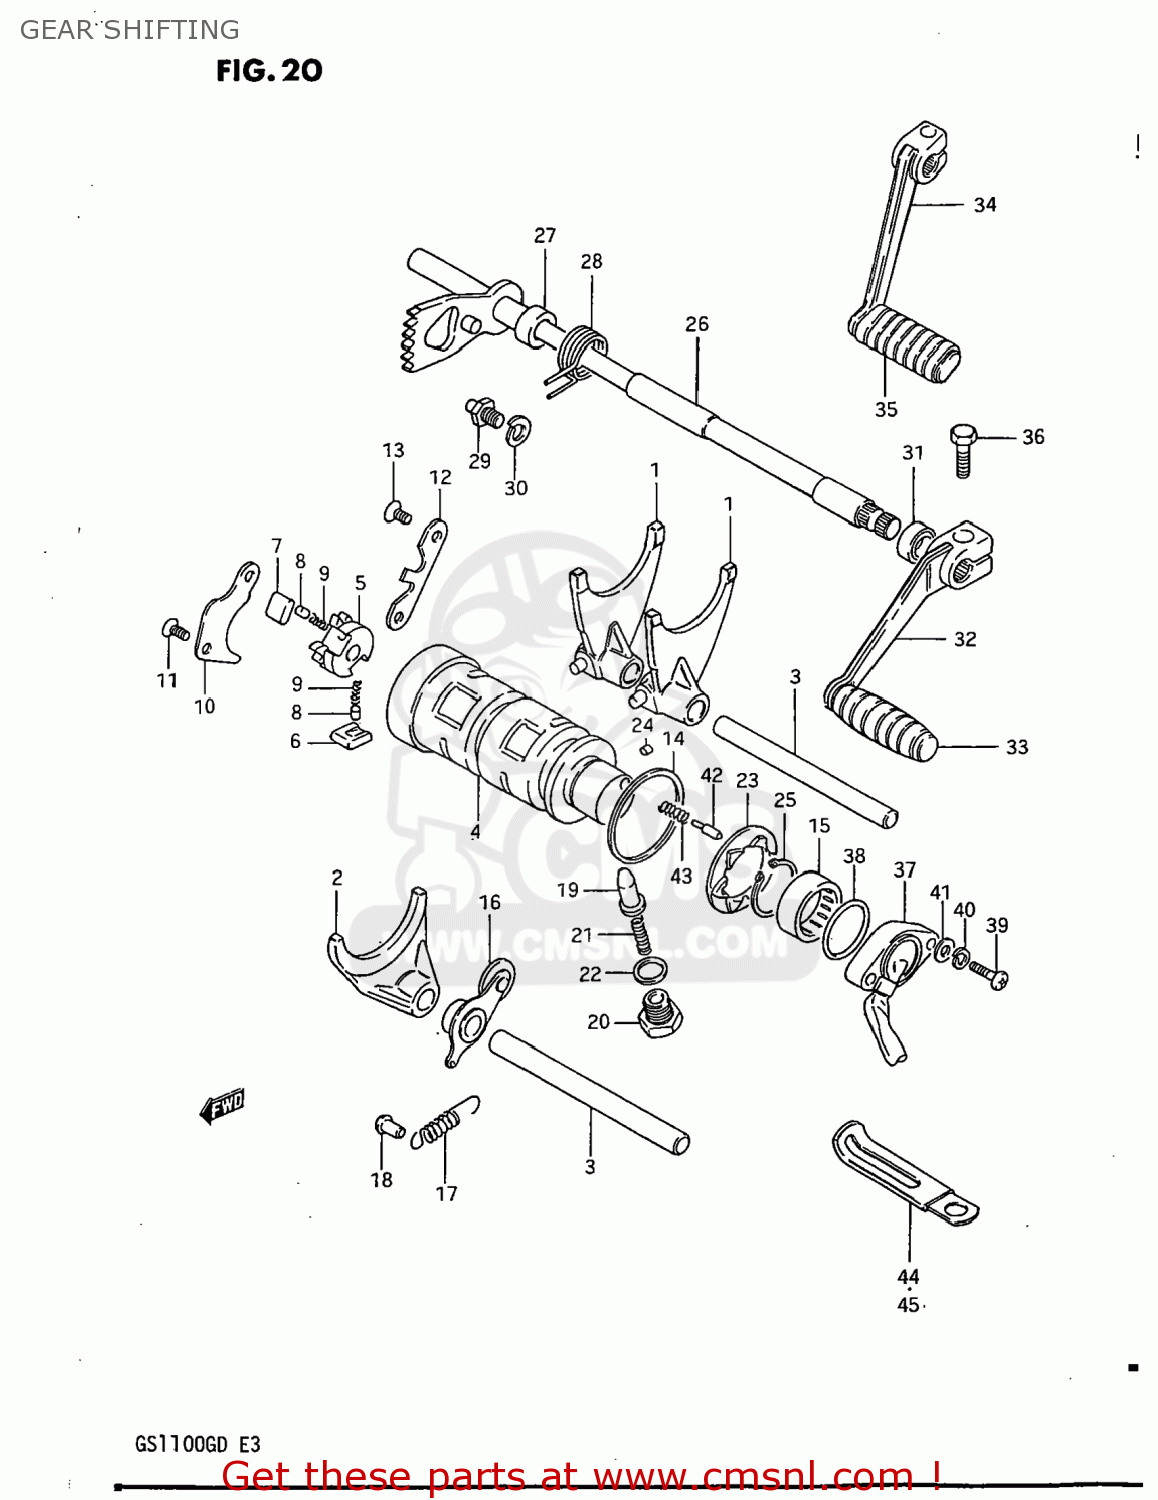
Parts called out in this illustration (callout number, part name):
1	FORK,GEAR SHIFT NO.1
2	FORK,GEAR SHIFT NO.3
3	SHAFT,GEAR SHIFT FORK
4	CAM,GEAR SHIFT
5	RETAINER,GEAR SHIFT CAM
6	PAWL,GEAR SHIFT NO.1
7	PAWL,GEAR SHIFT NO.2
8	PIN(5X8)
9	SPRING
10	LIFTER,GEAR SHIFT PAWL
11	SCREW
12	GUIDE,GEAR SHIFT CAM
13	SCREW
14	WASHER(40X45X1)
15	BEARING
16	STOPPER,GEAR SHIFTING
17	SPRING
18	RIVET
19	STOPPER,GEAR SHIFT CAM NO.2
20	HOLDER,GEAR SHIFT CAM STOP SPR
21	SPRING
22	GASKET(14X19.2X2) (NAS)
23	PLATE,GEAR SHIFT CAM STOPPER
24	PIN 4X6
25	CIRCLIP,25MM
26	SHAFT,GEAR SHIFT
27	SPACER (12X20X12)
28	SPRING
29	STOPPER,GEAR SHIFT CAM
30	WASHER
31	OIL SEAL
32	LEVER ASSEMBLY,GEAR SHIFTING
33	RUBBER,GEAR SHIFT PEDAL
34	LEVER ASSEMBLY,GEAR SHIFTING
35	RUBBER,PEDAL
36	BOLT
37	TERMINAL BASE ASSY,GEAR SHIFT
38	O-RING (D:2.4 ID:26.2)
39	SCREW 5X20
40	LOCK WASHER
41	WASHER
42	PIN(5X15.5)
43	SPRING
44	CLAMP L:35
45	CLAMP
